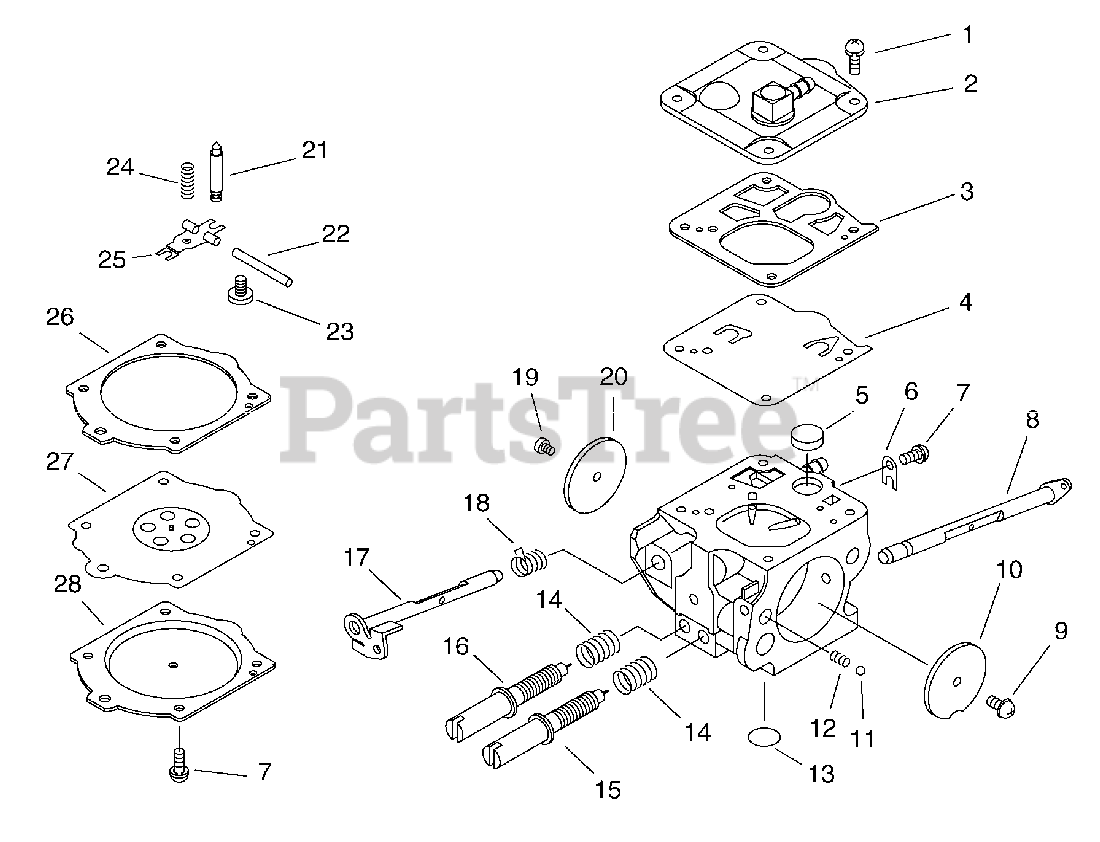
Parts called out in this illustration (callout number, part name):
1	SCREW
2	COVER, FUEL PUMP
3	GASKET, PUMP
4	DIAPHRAGM, PUMP
5	SCREEN, FUEL INLET
6	CLIP, THROTTLE SHAFT
8	SHAFT ASSY, CHOKE
10	VALVE, CHOKE
11	BALL, CHOKE
12	SPRING, CHOKE
13	PLUG, WELCH
14	SPRING, NEEDLE
15	NEEDLE, HIGH SPEED
16	NEEDLE, LOW SPEED
17	SHAFT ASSY, THROTTLE
20	VALVE, THROTTLE
21	VALVE, INLET NEEDLE
22	PIN, METERING LEVER
23	SCREW, METERING LEVER PIN
25	LEVER, METERING
26	GASKET, METERING DIAPHRAGM
27	DIAPHRAGM, METERING
28	COVER, DIAPHRAGM
